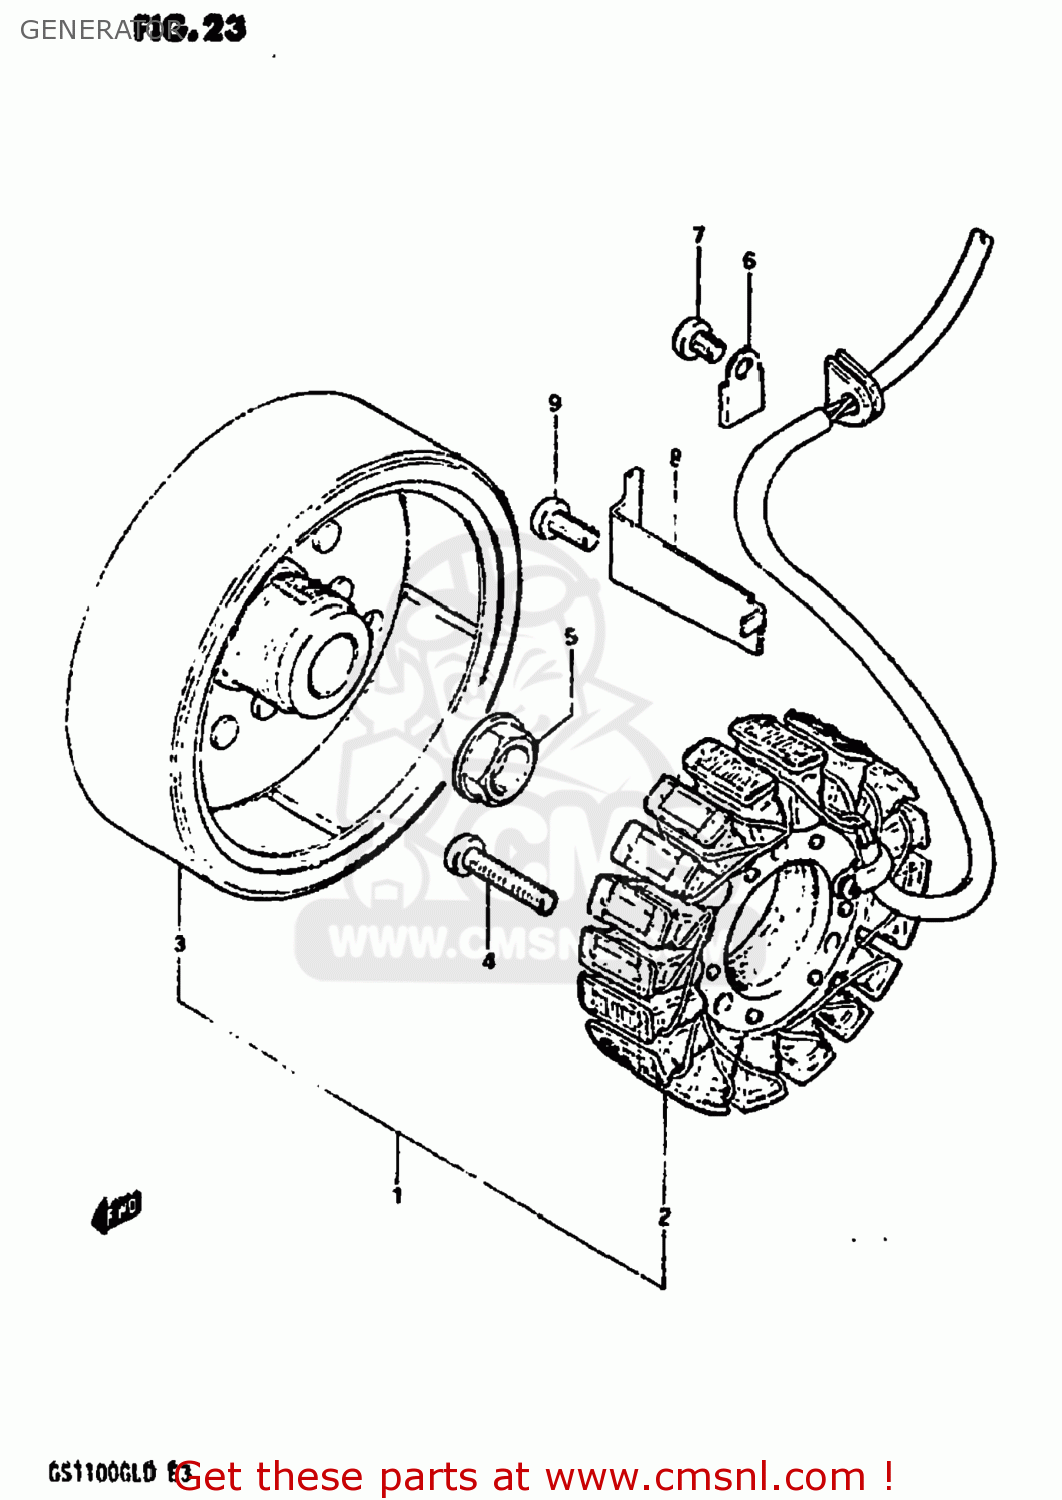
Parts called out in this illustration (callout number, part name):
1	GENERATOR ASSEMBLY
2	STATOR ASSEMBLY
3	ROTOR ASSEMBLY
4	SCREW 6X30
5	NUT,GENERATOR ROTOR
6	CLAMP,GENERATOR LEAD WIRE
7	SCREW
8	CLAMP,GENERATOR LEAD WIRE
9	SCREW
